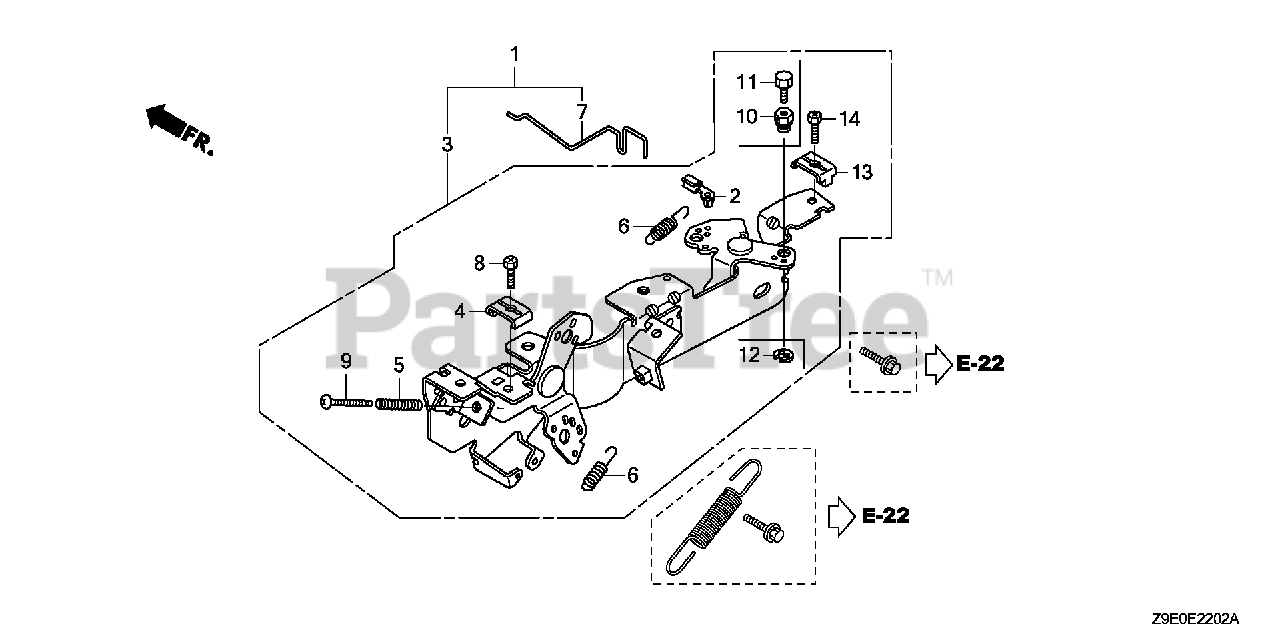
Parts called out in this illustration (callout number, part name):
1	CONTROL KIT
2	JOINT, ROD
3	CONTROL ASSY.
4	HOLDER, CABLE
5	SPRING, CONTROL ADJUSTING Use from Engine SN 2327377.
6	SPRING, CABLE RETURN
7	ROD, CHOKE CONTROL
8	BOLT, RECESSED (5X16)
9	SCREW, PAN (5X40)
10	HOLDER, WIRE
11	BOLT, RECESSED (4X6)
12	E-RING (5MM)
13	HOLDER, CABLE
14	BOLT, RECESSED (5X16)
